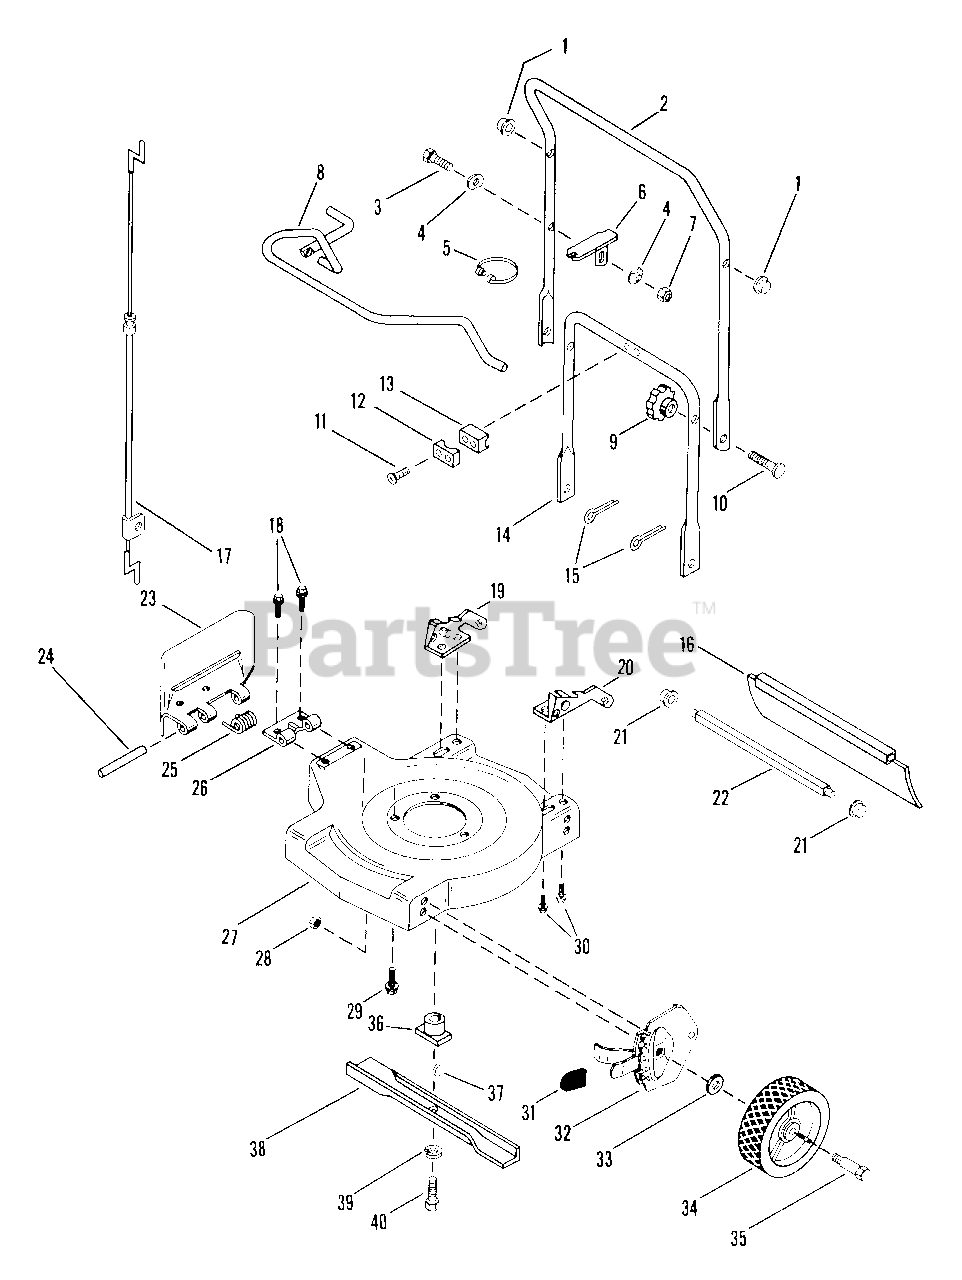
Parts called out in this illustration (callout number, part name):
1	NUT-PUSH .312 DIA. PAL
2	UPPER HANDLEBAR W/DECAL
3	BLT-HEX .25-20X1.25 PL GR5
4	WSHR-CURVED .281X.750X.060 PL
5	CABLE RETAINER
6	CABLE ANCHOR
7	NUT-LK-CTR .250-20 PL
9	FLUTED WING
10	BLT-RDHDSQNK .31-18X2.0 SHT PL
11	SCR-TAP 12-14X1.50 CROVH PL BT
12	ROPE GUIDE TOP
13	ROPE GUIDE BOTTOM
14	LOWER HANDLEBAR
15	PIN-COTR .09X.75 PL
16	REAR PROTECTIVE GUARD
17	ENGINE CABLE
18	BLT-SERHFWH .25-20X.50 PL
19	HANDLEBAR BRACKET R.H.
20	HANDLEBAR BRACKET
21	PUSH NUT, .25
23	DEFLECTOR ASSEMBLY
25	SG-TORS .055X.16X.938
27	18 INCH MOWER PAN W/DECALS
28	NUT-LK-CTR .375-16 GR A PL
29	SCR-TAP .375-16X1.0 HWH PL TR
30	SCR-TAP .250-20X.37 HWH PL TR
32	WHEEL HEIGHT ADJUSTOR ASSEMBLY
33	WSHR-FL-STL .382X.812X.023 PL
34	T/WHL ASSY
35	SHOULDER BOLT .50 X 1.51 YWZC
36	BLADE ADAPTOR
37	KEY-WDRF .156X.625X.25 SAE 6
39	WSHR-LK .375X.094 MED PL
40	BLT-HEX .38-24X2.00 PL GR5
41	TVS 90 LAUSON
